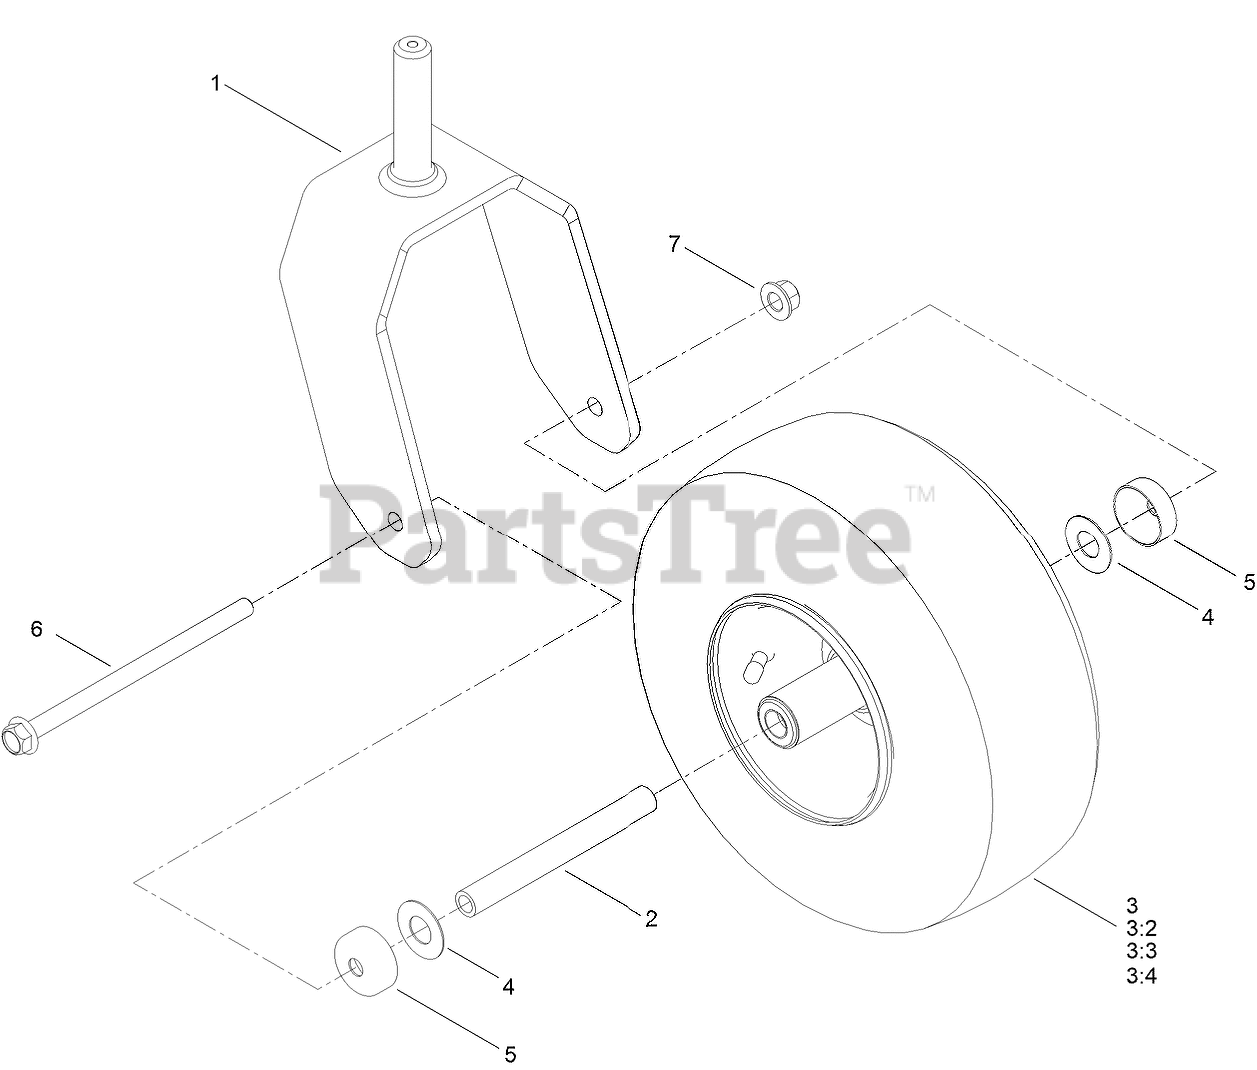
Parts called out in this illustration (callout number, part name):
1	FORK-CASTER
2	SPANNER-WHEEL
3	TIRE AND WHEEL ASM
3:4	BEARING
4	WASHER
5	GUARD-SEAL
6	SCREW-HHF
7	NUT-LOCK
